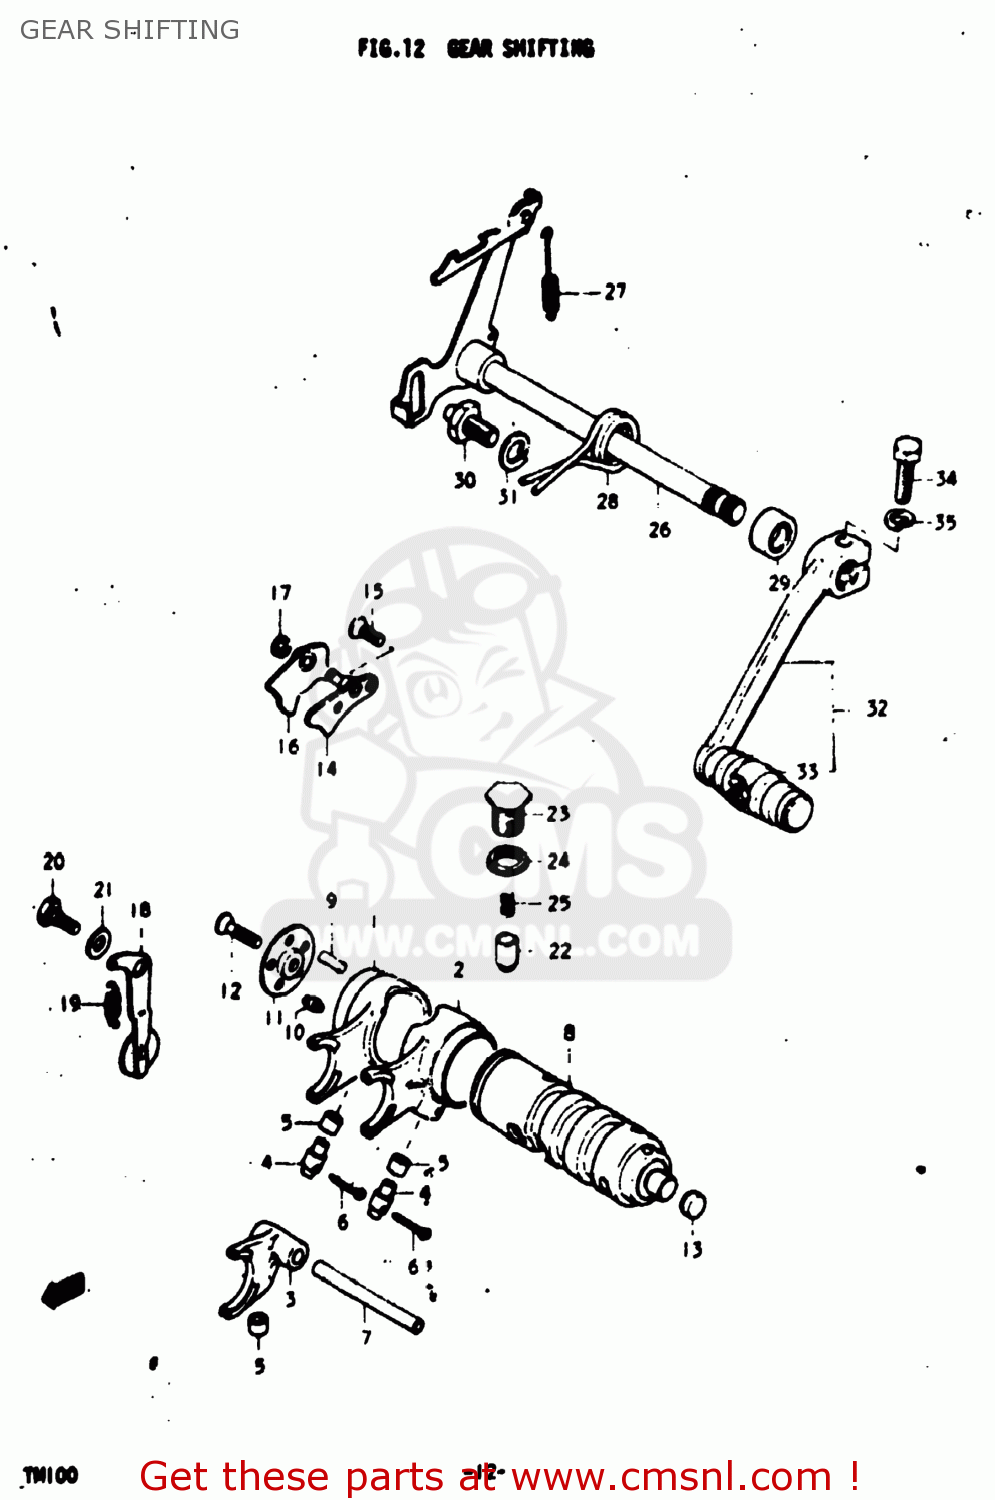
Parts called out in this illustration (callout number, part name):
1	FORK,GEAR SHIFT NO.1
2	FORK,GEAR SHIFT NO.2
3	FORK,GEAR SHIFT NO.3
4	PIN
5	SPACER
6	PIN 25X20
7	SHAFT,GEAR SHIFT FORK
8	CAM,GEAR SHIFT
9	ROLLER(4X13.8)
10	PIN
11	RETAINER,GEAR SHIFT CAM DR PIN
12	SCREW
13	PLUG
14	GUIDE,GEAR SHIFT CAM
15	SCREW
16	PAWL,GEAR SHIFTING CAM
17	E RING
18	STOPPER,SHIFT CAM
19	SPRING
20	BOLT(6X16.1)
21	WASHER(6.5X16X2.3)
22	STOPPER,GEAR SHIFTING
23	HOLDER,SHIFTING CAM STOPPER
24	GASKET(14X19.2X2) (NAS)
25	SPRING
26	SHAFT,GEAR SHIFT
27	SPRING
28	SPRING
29	OIL SEAL
30	STOPPER,GEAR SHIFT ARM
31	LOCK WASHER
32	LEVER ASSEMBLY,GEAR SHIFTING
33	RUBBER,GEAR SHIFT PEDAL
34	BOLT
35	LOCK WASHER
